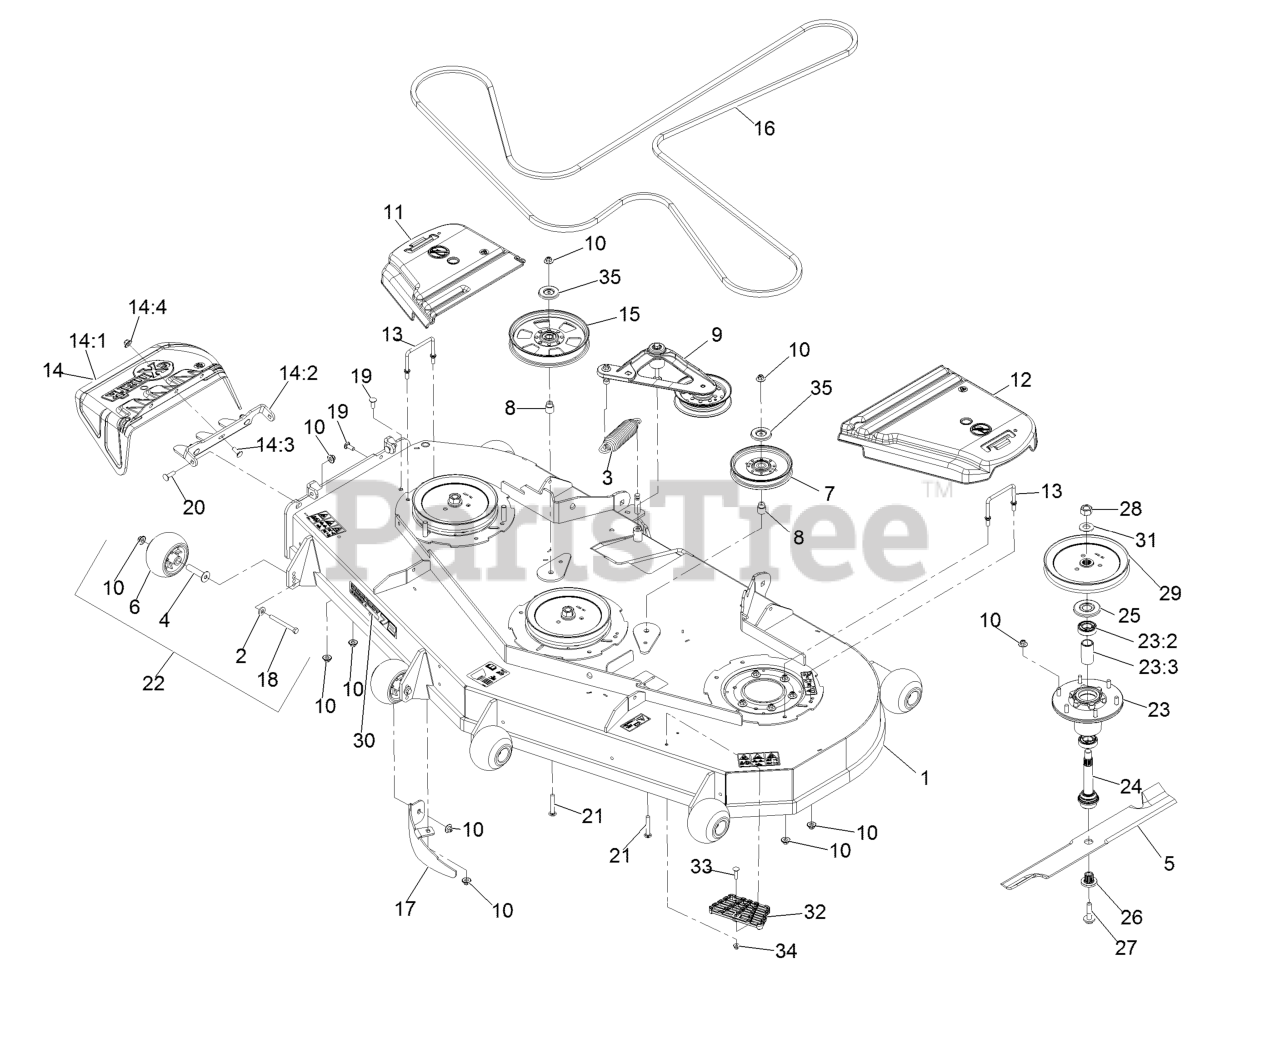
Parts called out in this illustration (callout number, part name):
1	ASM,Deck W/Decals 724
2	Washer-Spring Disc 3/8
3	Spring-Extension
4	Axle, Roller
5	Blade, Solid (72")
5	Blade, Low Lift (72")
5	Blade, Mulching (72")
5	Blade, Notched (72")
5	Blade-Extreme 2, 24.50"
6	Roller-Anti-Scalp
7	Idler-Pulley
8	Bushing, Idler
9	Deck Idler ASM
10	Nut-Nyloc 3/8-16 Flg
11	Cover-Belt, RH
12	Cover-Belt, LH
13	Wireform-Cover
14	ASM,Discharge Chute
14:1	Chute, Discharge
14:2	Bracket,Discharge Chute
14:3	Bolt-Carriage 3/8-16 X 1
14:4	Nut-Nyloc 3/8-16 Flg
15	Pulley-Idler, Flat
16	Belt-V
17	Baffle-Dogleg, Lz72
18	Screw-HH 3/8-16 X 3 3/4 GR 8
19	Bolt-Carriage 3/8-16 X 1
20	Bolt-Carriage 3/8-16 X 1 1/4
21	Bolt-Carriage 3/8-16 X 2 1/2
22	Kit, Anti-Scalp Roller
23	ASM-Cutter Hsg With Bearings
23:2	Bearing-Ball
23:3	Spacer-Bearing
24	ASM-Spindle And Seal
25	Guard,Bearing Top .989
26	Bushing, Splined
27	Screw-Sems 1/2-20 X 2.19
28	Nut-Hex
29	Sheave,Blade Drive 8.74
30	Decal, 724
31	Washer-Spring Disc 3/4
32	Step-Deck
33	Screw-CARR
34	Nut-HF, NI
35	Shield-Dust
